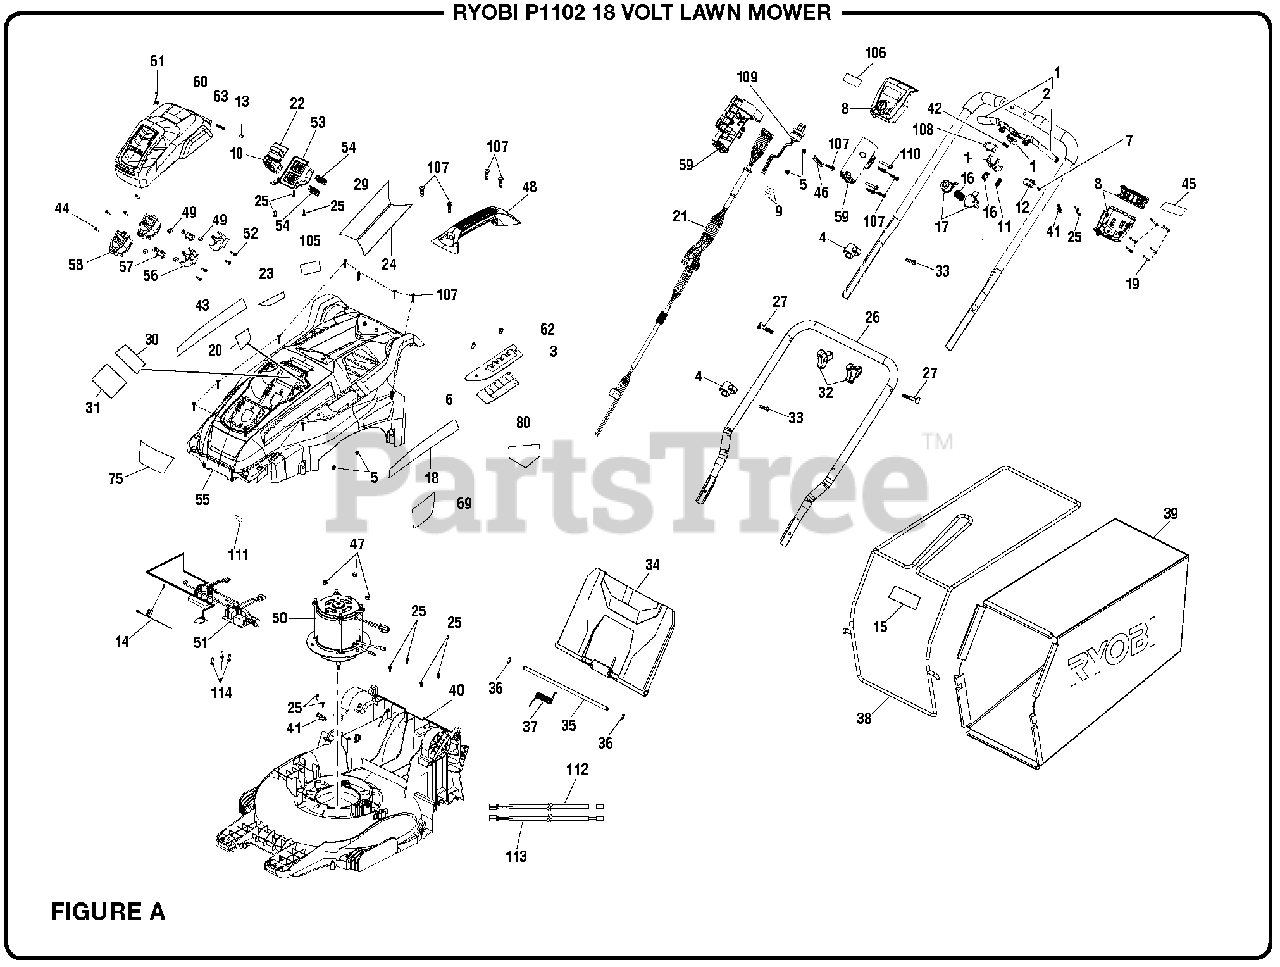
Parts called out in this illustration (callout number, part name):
1	Trigger Handle Assembly
2	Upper Handle Assembly
3	Height Adjustment Plate
4	Cord Clamp
5	Lock Nut (M5)
6	Dust Gasket
7	Screw (M4 x 10 mm, T20 Torx Pan Hd.)
8	Trigger Housing Assembly
9	Wire Connector (Closed End)
10	Start Key
11	Compression Spring
13	Battery Door Axle
14	Lead Wire w/Terminal Block
15	Bag Door Label
16	Button Return Spring
17	Start Button Assembly
18	Lithium Label (Left)
19	Screw (M4 x 30 mm, T15 Torx Pan Hd.)
20	Fuel Gauge Label
21	Starter Cable (Long)
22	Slide Door
23	Icon Warning Label
24	Warning Icon Label (Right)
25	Screw (M4 x 16 mm, T20 Torx Pan Hd.)
26	Lower Handle
27	Screw (M8 x 57 mm)
29	Warning Icon Label (Left)
30	Star Key Label (Eng)
31	Start Key Label (FR/SP)
32	Knob (526906001)
33	Screw (M3 x 20 mm)
34	Rear Discharge Door
35	Rear Door Axle
36	Retaining Ring (E)
37	Torsion Spring (Rear Door)
38	Bag Frame
39	Bag
41	Cord Clip
43	Lithium Label (Right)
44	Screw (M4 x 16 mm)
45	Starting Instructions Label
46	Cord Clip
47	Lock Nut (M6)
49	Rubber Block
51	Start Circuit Board
52	Screw (M4 x 16 mm, T20 Torx Socket Pan Hd.)
53	Key Holder Assembly
54	Female Terminal
55	Deck Cover
56	Press Cover (Battery Connect)
57	Plate (Battery Connect)
58	Base (Battery Connect)
59	AC Plug Housing Assembly
60	Battery Cover
61	Torsion Spring (Battery Door)
62	Screw (M5 x 16 mm, Pan Hd.)
63	Pressure Spring
69	Height Adjust Label
75	Ryobi Logo Label (Front)
80	Cut Finger Label
105	Data Label
106	Ryobi Logo Label (Handle)
107	Screw (M4 x 20 mm)
108	Micro Switch
109	Plug Wire
110	Screw (M5 x 30 mm)
111	Wire Connector (Closed End)
112	Lead Wire (Red)
113	Lead Wire (Brown)
114	Screw (M3 x 8 mm, Pan Hd.)
